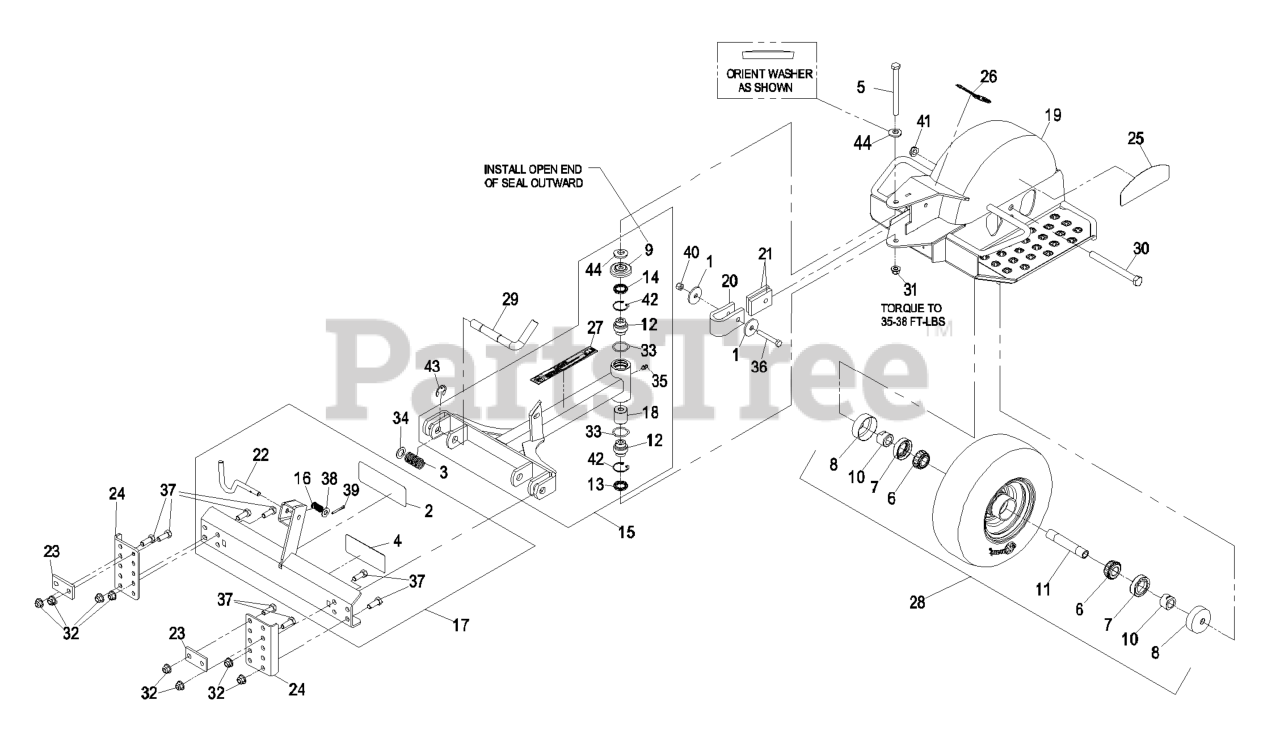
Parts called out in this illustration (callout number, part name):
2	DECAL,BELT DRIVE
3	SPRING,HITCH RELEASE
4	DECAL,SULKY WARNING
5	SCREW-HH
6	BEARING-CONE, TAPERED ROLLER
7	SEAL-CASTER
8	GUARD-SEAL
9	GUARD-TOP
10	SPACER-NUT
12	BEARING-SPHERICAL
13	SEAL-LIP, DOUBLE
14	SEAL-LIP, SINGLE
15	ASM,PULL ARM W/BRGS-DECAL
16	SPRING,LOCK PIN
17	ASM,PULL FRAME
18	SPACER-HYDRO CONTROL, LH
19	ASM,SULKY FRAME W/DECALS
21	PAD,STOP
22	PIN LATCH
23	PLATE,BACK-UP (PLATED)
24	PLATE,ADAPTER
25	DECAL,STANDON
26	DECAL,EXMARK
27	DECAL,SULKY
28	ASM,WHEEL AND BEARING
29	PIN,PULL ARM (PLATED)
30	SCREW-HH
32	NUT-HF, NI
34	WASHER-FLAT
35	FITTING-GREASE
36	SCREW-HH
37	SCREW-HH
38	WASHER-FLAT
39	PIN-COTTER
40	NUT-LOCK, NI
41	NUT-HEX
42	RING-SNAP
44	WASHER-BELLEVILLE
